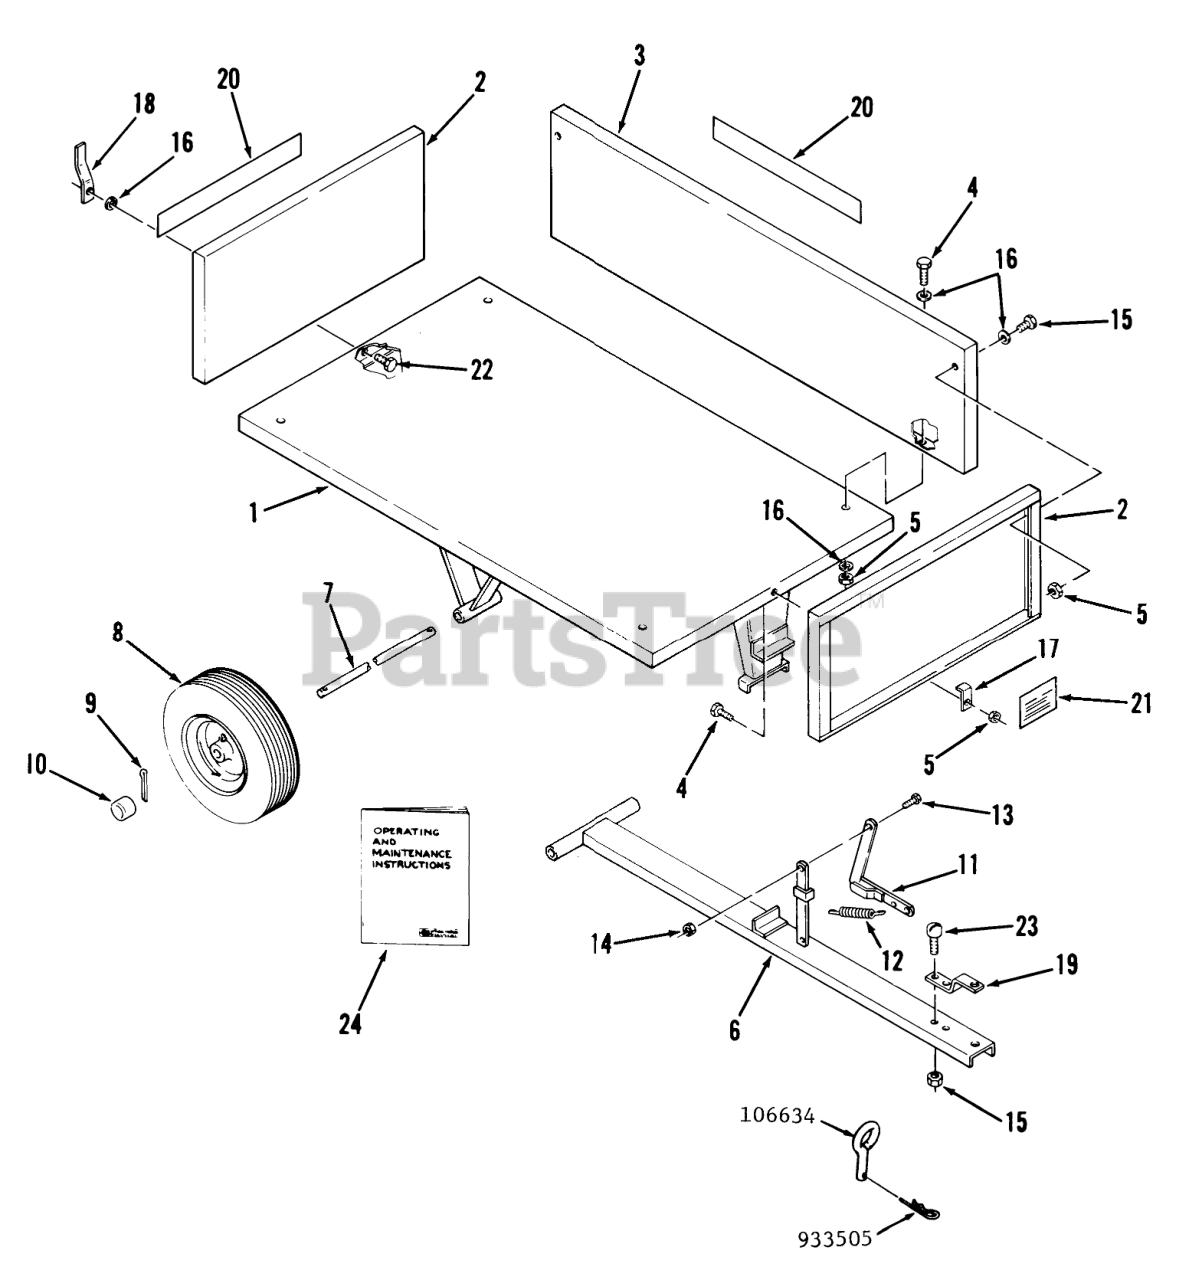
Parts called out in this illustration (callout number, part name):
1	Bed Assembly
2	Front and Rear Gate
3	Side Gate
4	Hex Bolt 3/8-16 x 1
5	E. S. Nut 3/8-16
6	Drawbar Assembly
8	Wheel Assembly (6.50 x 8-16)
9	Cotter Pin
10	HUB CAP
11	Latch Assembly
12	SPRING
13	Bolt
14	Nut
15	Bolt
16	Washer
17	Latch-Front Gate
18	Latch-Rear Gate
19	CLEVIS-BAR
20	Decal
21	Weight Limit Decal
22	Bolt
23	Truss Hd. Bolt 3/8-16 x 3/4
24	Operating and Maintenance Instructions
24	Wheel
24	Tire
24	Wheel Bearing
